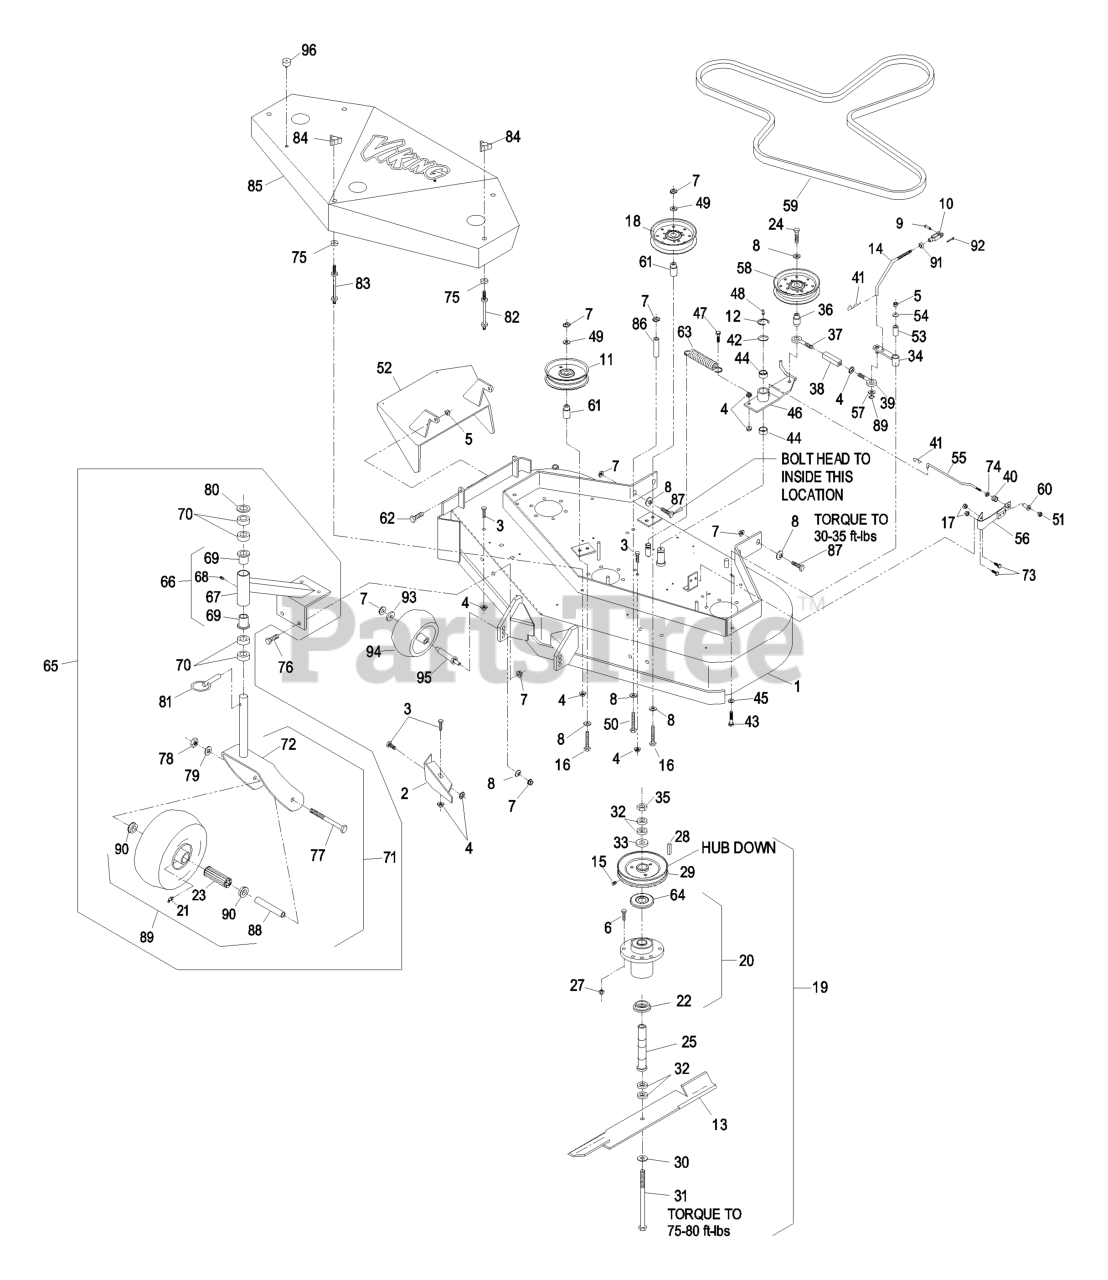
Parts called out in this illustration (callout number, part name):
1	DECK-SERVICE, 48
2	BAFFLE-DOGLEG
3	SCREW-HH
5	NUT-LOCK, NI
6	SCREW-HH
7	NUT-HHF, WHIZ
8	WASHER-BELLEVILLE
9	PIN-CLEVIS
10	YOKE-ADJUSTABLE
11	PULLEY-IDLER
12	RING-RETAINING, EXT
14	ARM-LINKAGE, ASSIST
15	SCREW-SET
16	SCREW-HH
17	NUT-LOCK, NI
19	ASM, CUTTER HOUSING OUTER
20	KIT, CUTTER HOUSING
21	FITTING-GREASE
22	SPACER-GUARD, BOTTOM
23	BEARING
24	SCREW-HH
25	TUBE-SPINDLE, SHORT
26	RING-RETAINING, EXT
27	NUT-LOCK, NI
29	SHEAVE
30	WASHER-SPRING
31	SCREW-CAP, HH
33	WASHER-RETAINER, SHEAVE
34	ARM-ASSIST, 32/36
35	NUT-HEX
36	BUSHING-ENGAGEMENT
37	EYEBOLT-THREAD, LH
38	BODY-TURNBUCKLE
39	EYEBOLT-THREAD, RH
40	SPRING-COMPRESSION
41	PIN-COTTER
42	WASHER-SPINDLE
43	SCREW-HH
44	SLEEVE-BEARING
45	WASHER-SPRING
46	IDLER ARM ASM
47	SCREW-HH
48	FITTING-GREASE
49	WASHER-FLAT
50	SCREW-HH
51	NUT-LOCK, NI
52	WLD,CHUTE 48
53	TUBE-PIVOT
54	WASHER-FLAT
55	ROD-BRAKE
56	PAD AND SPRING ASM
57	WASHER-PLAIN
59	BELT,BLADE 48
60	SPACER-FLANGED
62	SCREW-HH
63	SPRING-EXTENSION
64	GUARD-BEARING, TOP
66	ASM,CSTR SUPPORT W/WEIGHT
68	FITTING-GREASE
69	BEARING-FLANGED
70	SPACER-CASTER
71	ASM,CASTER/WHEEL
73	SCREW-HH
74	RING-PUSH ON
76	SCREW-HH
77	SCREW-HH
78	NUT-HH
79	WASHER-LOCK
80	WASHER-FLAT
82	STUD-SHIELD, BELT (SHORT)
83	STUD-SHIELD, BELT (LONG)
84	KNOB-3 PRONG
87	SCREW-HH
89	KIT, SP CASTER WHEEL REPL
90	BUSHING
91	NUT-HEX
92	PIN-COTTER
94	ROLLER-SCALP, ANTI
